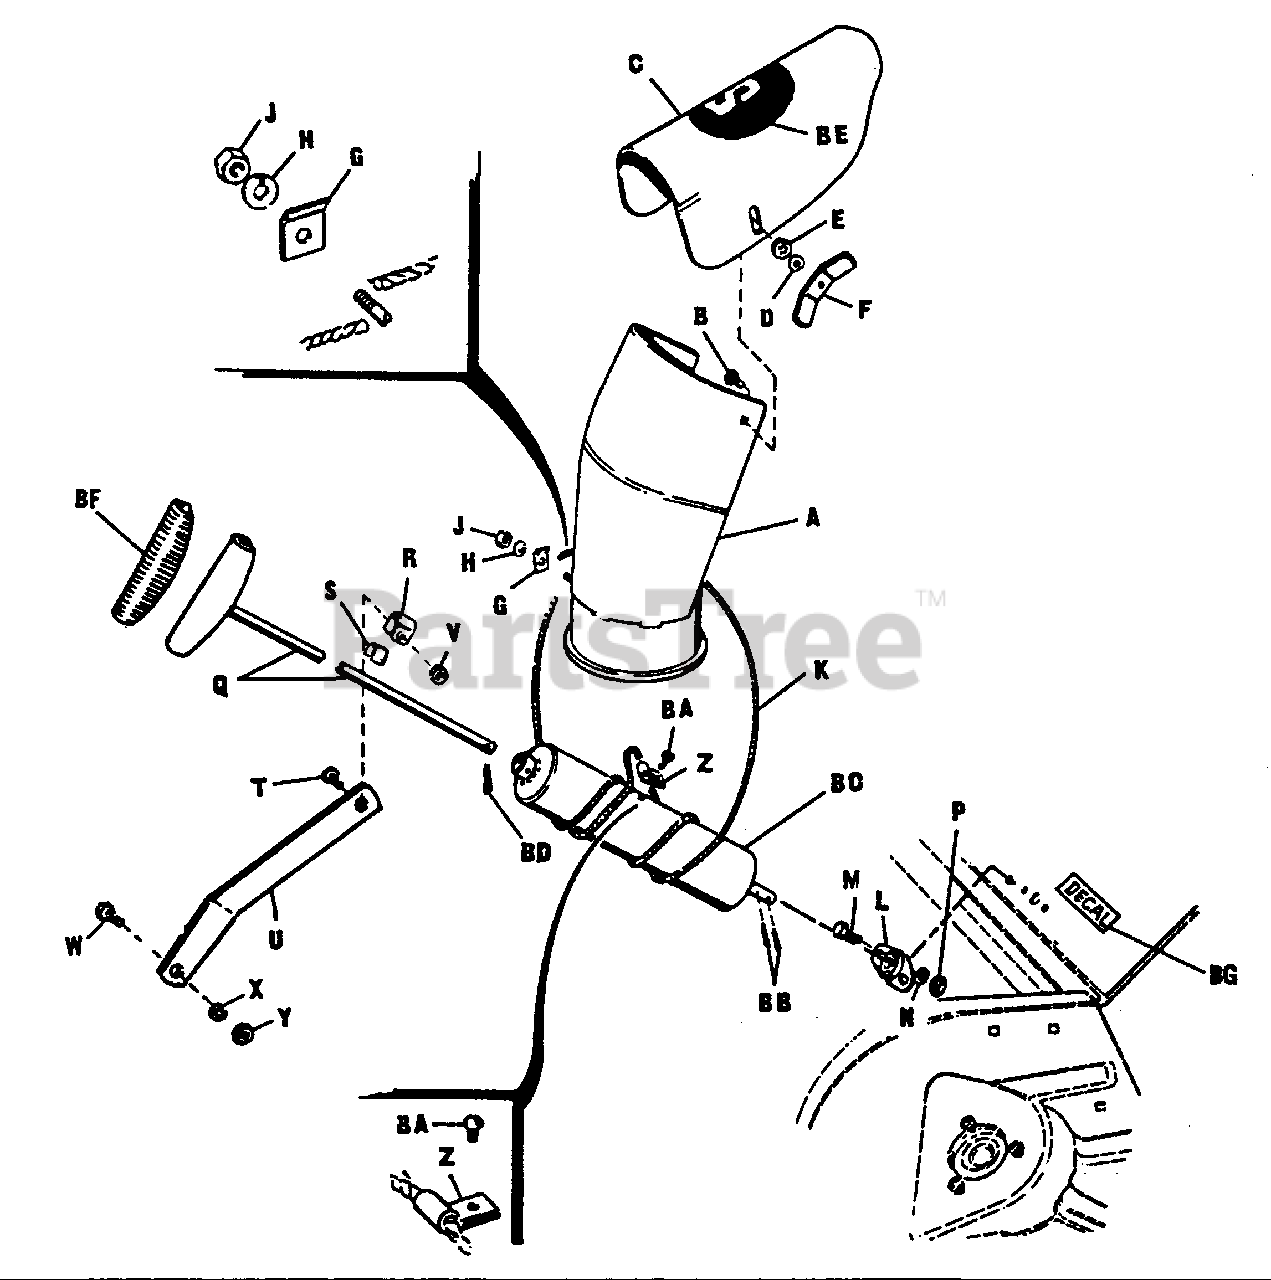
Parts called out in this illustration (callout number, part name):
A	Spout Assembly
B	Carriage Bolt, 5/16"-18 x 3/4"
C	Spout Extension
D	Plain Washer, 3/8"
E	Special Hex. Lock Washer, 3/8"
F	NUT, Wing, 5/16-18
H	Lock Washer, 5/16"
J	Full Hex. Nut, 5/16"-18
K	Spout Cord
M	Hex Capscrew, 1/4"-20 x 5/8"
N	Lock Washer, 1/4"
P	Full Hex. Nut, 24"-20
S	Guide Liner
T	Hex. Capscrew, 5/16"-18 x 1-1/4"'
U	Rod Guide Support
V	Full Hex. Lock Nut, 5/16"-18
W	Hex. Capscrew, 3/8"-16 x 1-1/4"
X	Lockwasher, 3/8"
Y	Hex. Nut, 3/8"-16
BA	Self-Tapping Screw, 1/4"-20 x 1/2"
BB	Cotter Pin, 1/8" x 3/4"
BC	Control Tube, W/Socket
BD	Cotter Pin, 5/32" x 1"
BF	Cover Handle
BG	Safety Decal
